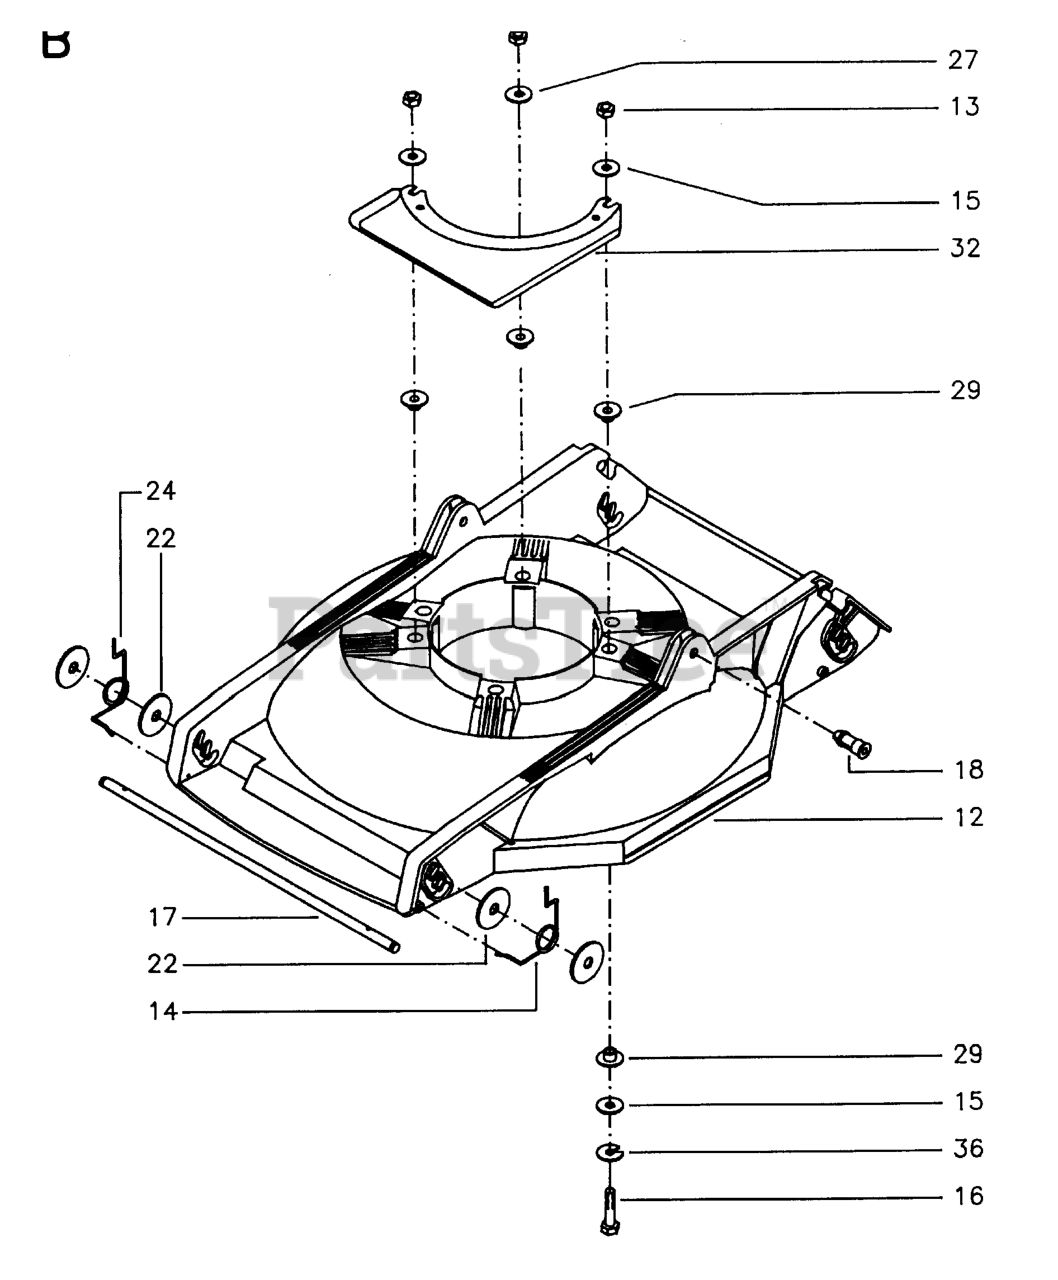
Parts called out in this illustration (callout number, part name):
13	LOCKNUT M8
29	FLANGE BRG.
36	SPRING WASHER
